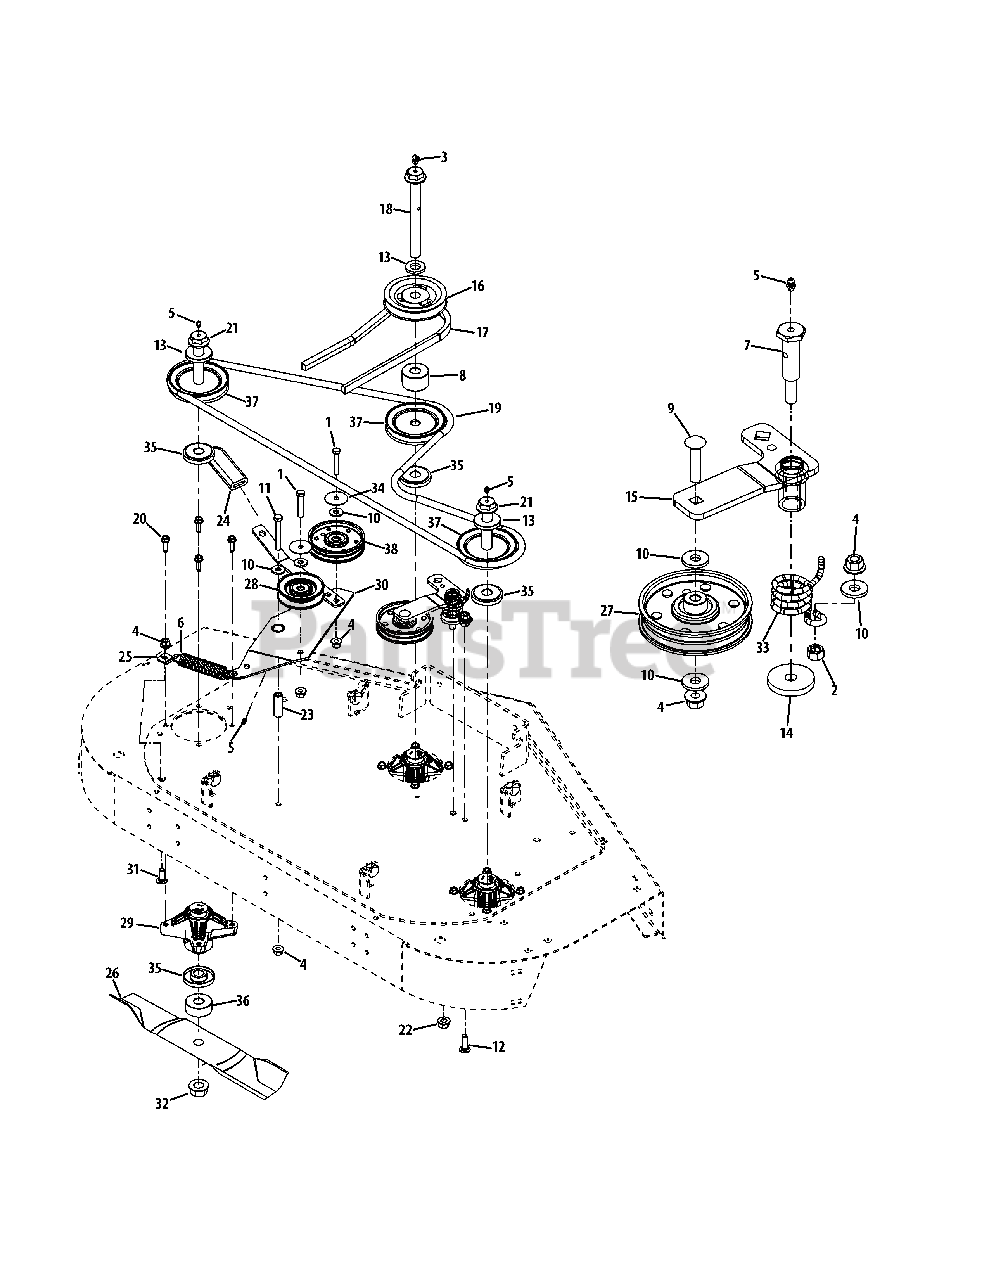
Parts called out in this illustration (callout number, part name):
1	Hex Screw, 3/8-16 x 2.00
2	Nut, 3/8-16
3	Grease Fitting, 1/4-28 x .788
4	Flange Counterlock Nut, 3/8-16
5	Grease Fitting, 1/4-28
6	Extension Spring, 1.00 x 5.00 x .125
7	Shoulder Bolt, .625 x 1.95
8	Spacer, .760 x 2.00 x 1.27
9	Carriage Bolt, 3/8-18 x 1.75
10	Washer, .406 x 1.00 x .105
11	Hex Screw, 3/8-16 x 3.00
12	Carriage Bolt, 3/8-16 x 1.25
13	Spacer, 2.0 x .75 ID x .31
14	Washer, .438 x 1.75 x .250
15	Idler Arm Assembly
15	Sleeve Bearing, .628 x .753 x .625
17	V-Belt
18	Hex Screw, 3/4-16 x 7.7
19	V-Belt
20	Hex Flange Screw, 5/16-18 x 1.00
21	Hex Flange Screw, 3/4-16 x 5.85
22	Flange Counterlock Nut, 7/16-14
23	Spacer, .390 x .625 x 1.88
24	Flat Grip, 1.0 x 3.2 x .25
25	Spring Mount Bracket
26	Hi-Lift Blade, 17.0
27	Idler Pulley
28	Idler Pulley
29	Spindle Assembly
30	Double Idler
30	Sleeve Bearing, .628 x .753 x .625
31	Carriage Bolt, 3/8-16 x 1.00
32	Flange Lock Nut, 3/4-16
33	Torsion Spring
34	Washer, .406 x 1.92 x .060
35	Deck Spindle Spacer
36	Spacer, .760 x 2.000 x .790
38	Idler Pulley
